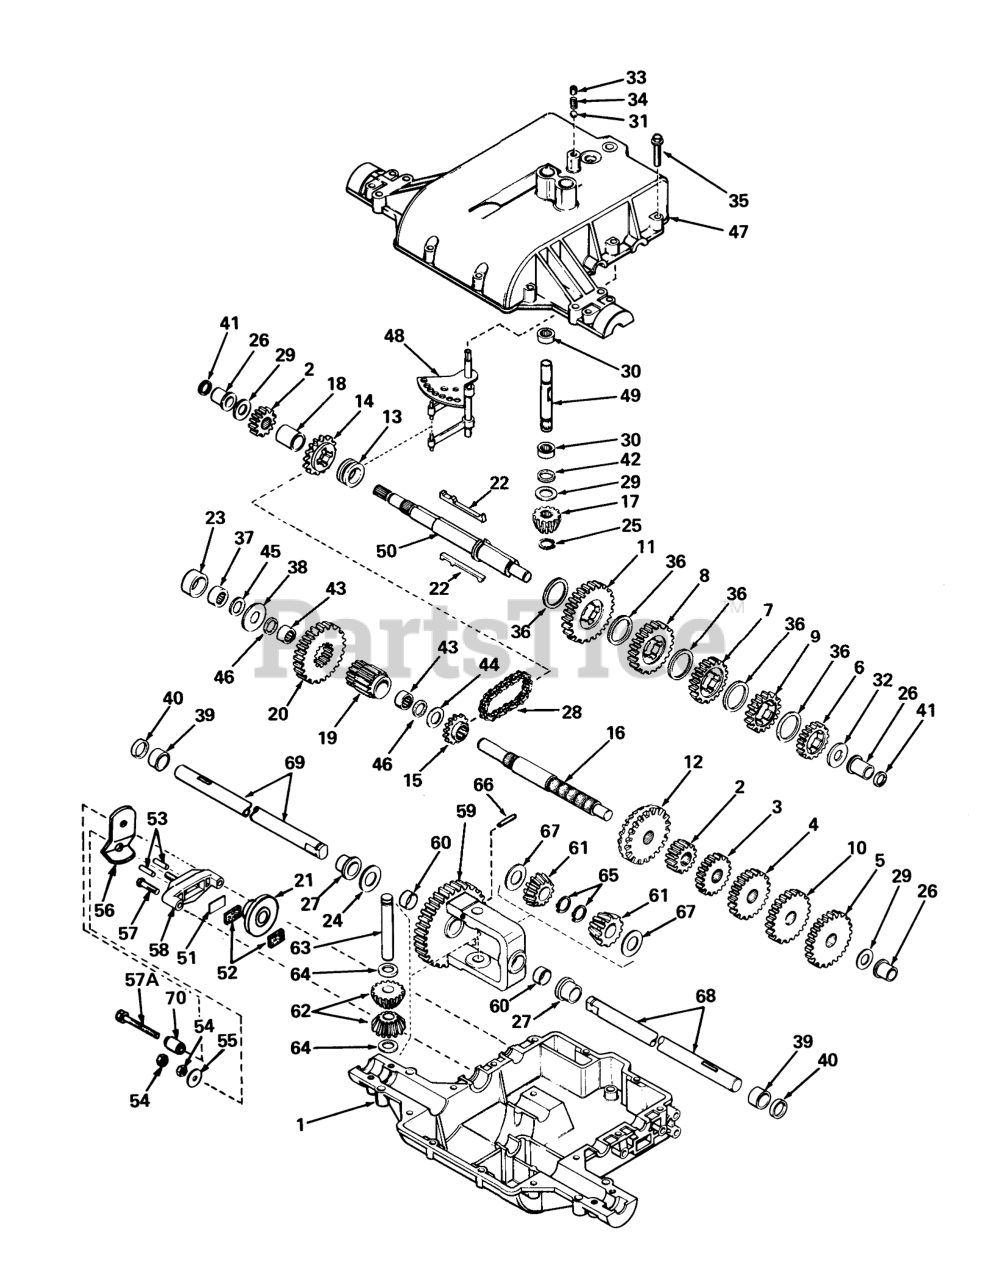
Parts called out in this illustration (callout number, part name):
1	Case, Transaxle
2	Gear-Spur 15 Teeth
3	Gear, Spur (20 teeth)
4	Gear, Spur (25 teeth)
5	Gear, Spur (30 teeth)
6	Gear-Spur 20 teeth
7	Gear, Spur (25 teeth)
8	Gear, Spur (30 teeth)
9	ASpur Gear (22 Teeth)
10	Gear, Spur (28 teeth)
11	Gear-Spur, 35 Teeth
12	Gear, Bevel (42 teeth)
13	Collar-Shift
14	Sprocket (14 Teeth)
15	Sprocket 10t
16	Shaft-Counter
17	Bevel Pinion, Input
18	Spacer
19	Pinion-Output
20	Gear-Output
23	Spacer
24	Washer
25	Ring-Retainer
26	Bushing, Flanged
27	Bronze Bearing
28	Chain, Roller (#41 Chain, 22 Links)
29	Washer
30	Bearing-Needle
31	Ball-Steel
32	Washer
33	Screw-Set
34	Spring
35	Ring Set (.020 O S)
36	Washer
37	Bearing-Needle
38	Washer-Flat
39	Bearing-Cartridge
40	Seal Oil
41	Ring-Square Cut
42	O Ring
43	Bearing-Needle
44	Washer-Flat
45	Ring-Square Cut
46	Ring-Square Cut
47	Cover, Transaxle
48	Rod & Fork Assembly
49	Shaft, Input
50	Shaft, Brake
51	Brake Pad Plate
52	Brake Pad
53	Dowel Pin
54	Locknut
55	Washer
56	Lever-Brake
57	Ring Set (.020 O S)
57A	Screw-Hex. Flange
58	Holder-Brake Pad
59	Gear Assembly, Differential (Incl. 2 of No. 60)
60	Bushing
61	Bevel Gear
62	Gear Pinion
63	Drive Pin
64	Thrust Washer
65	Snap Ring
66	Pin-Roll
67	Washer
68	Axle (14-7/8" long)
69	Axle (13" Long)
70	Spacer
